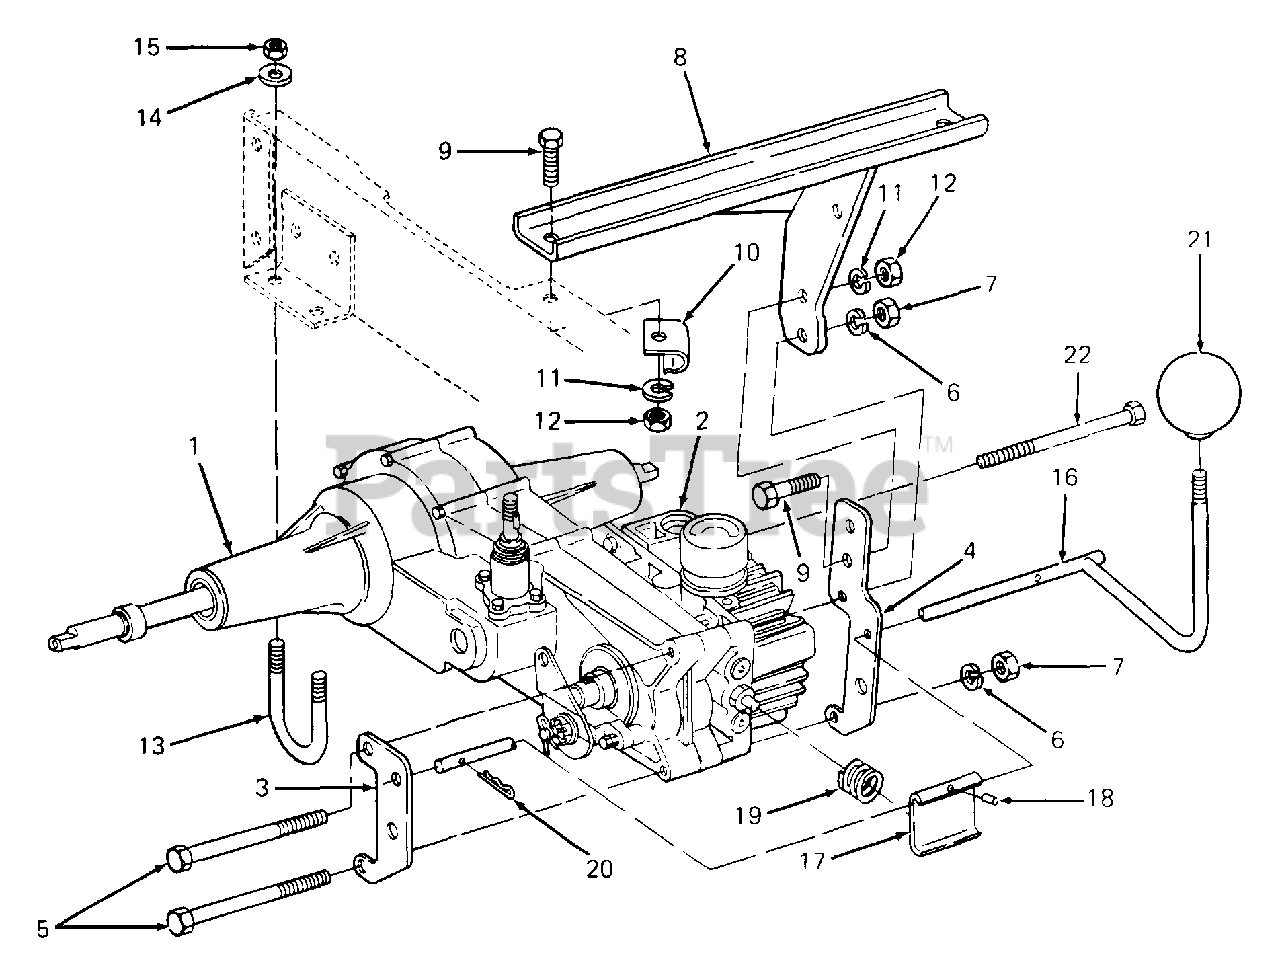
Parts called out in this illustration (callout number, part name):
1	Transaxle
2	Pump, Hydro
3	Bracket Transmission Dump Valve
4	Bracket Transmission Dump Valve Torque
5	Screw, Hex Cap, 5/16-18 X 4.5 Lg GR5
6	Washer, Lock, 5/16
7	Nut, Hex, 5/16-18 GR5
10	Clip, Cable
11	Washer, Lock, 3/8
12	Nut, Hex, 3/8-16 GR5
13	U-Bolt, 5/16-18 X 1.75 Lg
14	Washer, Bell, .345 X .88 X .060 Thk
15	Nut, Hex Center Lock, 5/16-18 GR5
16	Rod, Dump Valve
17	Lever, Dump Valve
18	Pin, Spiral Spring, 1/8 Dia X .75 Lg
19	Spring, Compression
20	Pin, Internal Cotter
21	Knob, Ball, 1/4-20 Trd
22	Bolt, Hex Patch, 5/16-18 X 4.5 Lg GR5
